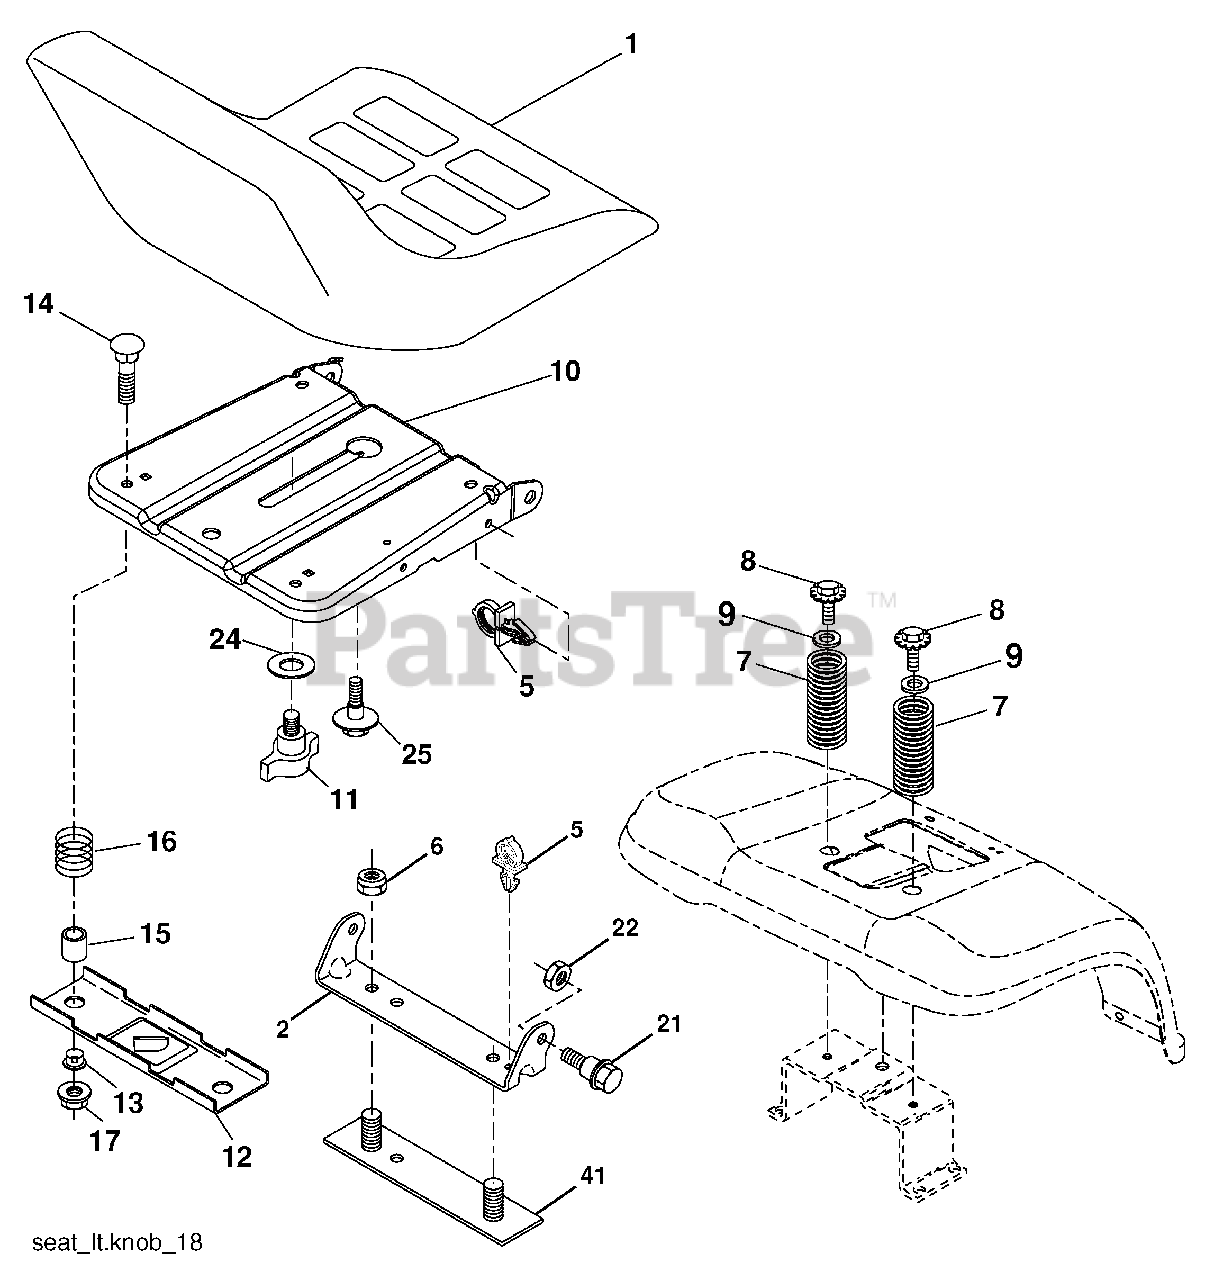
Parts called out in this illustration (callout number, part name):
2	Bracket Seat Pivot
5	Clip Push-In Hinged
6	Nut Lock Hex w/Ins. 3/8 - 16
7	Spring Seat Cprsn. 2 250 Blk. Zi.
8	Screw 3/8-16 x 1.5
9	Washer 13/32 x 1 x 14 Ga.
10	Pan Pnt. Seat
11	Knob Seat
12	Bracket Pnt. Mounting Switch
13	Bushing Snap Blk. Nyl.
14	Bolt Rdhd. Sht. Nk. 1/4 - 20 x 1 -1/2
15	Spacer Split .28 x .88
16	Spring Cprsn.
17	Nut Lock 1/4 Lge. Flg.
21	Bolt Shoul der 5/16-18 unc-2A
22	Nut Lock Hex w/Ins. 5/16 - 18
24	Washer 17/32 x 1-3/16 x 12 Ga.
25	Bolt Shoul der 5/16-18 x .62
41	Strap Asm. Fender
